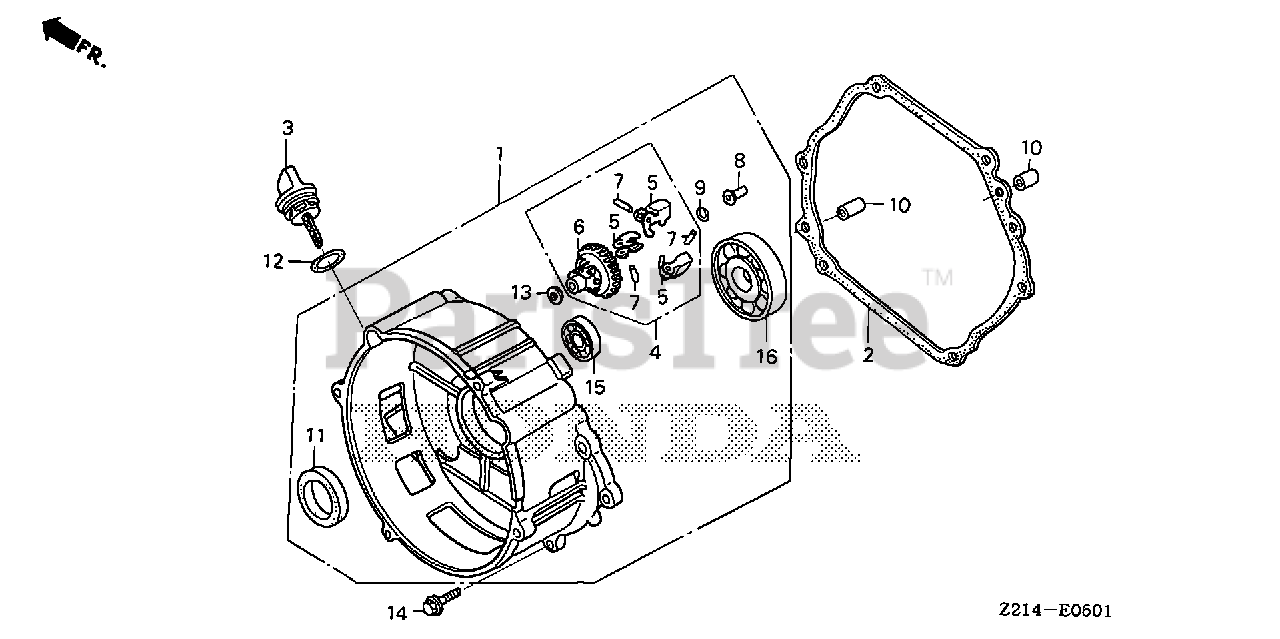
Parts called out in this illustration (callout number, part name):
1	COVER ASSY., CRANKCASE (E-TYPE)
2	GASKET, CASE COVER
2	GASKET, CASE COVER (NINGBO SIL GASKET)
3	CAP, OIL FILLER
4	GOVERNOR ASSY.
5	WEIGHT, GOVERNOR
6	HOLDER, GOVERNOR WEIGHT
7	PIN, GOVERNOR WEIGHT
8	SLIDER, GOVERNOR
9	CLIP, GOVERNOR HOLDER
10	PIN, DOWEL (8X12)
11	OIL SEAL (35X52X8)
12	O-RING (26X2.7)
13	WASHER, PLAIN (6MM)
14	BOLT, FLANGE (8X40)
15	BEARING, RADIAL BALL (6202)
16	BEARING, RADIAL BALL (6207)
